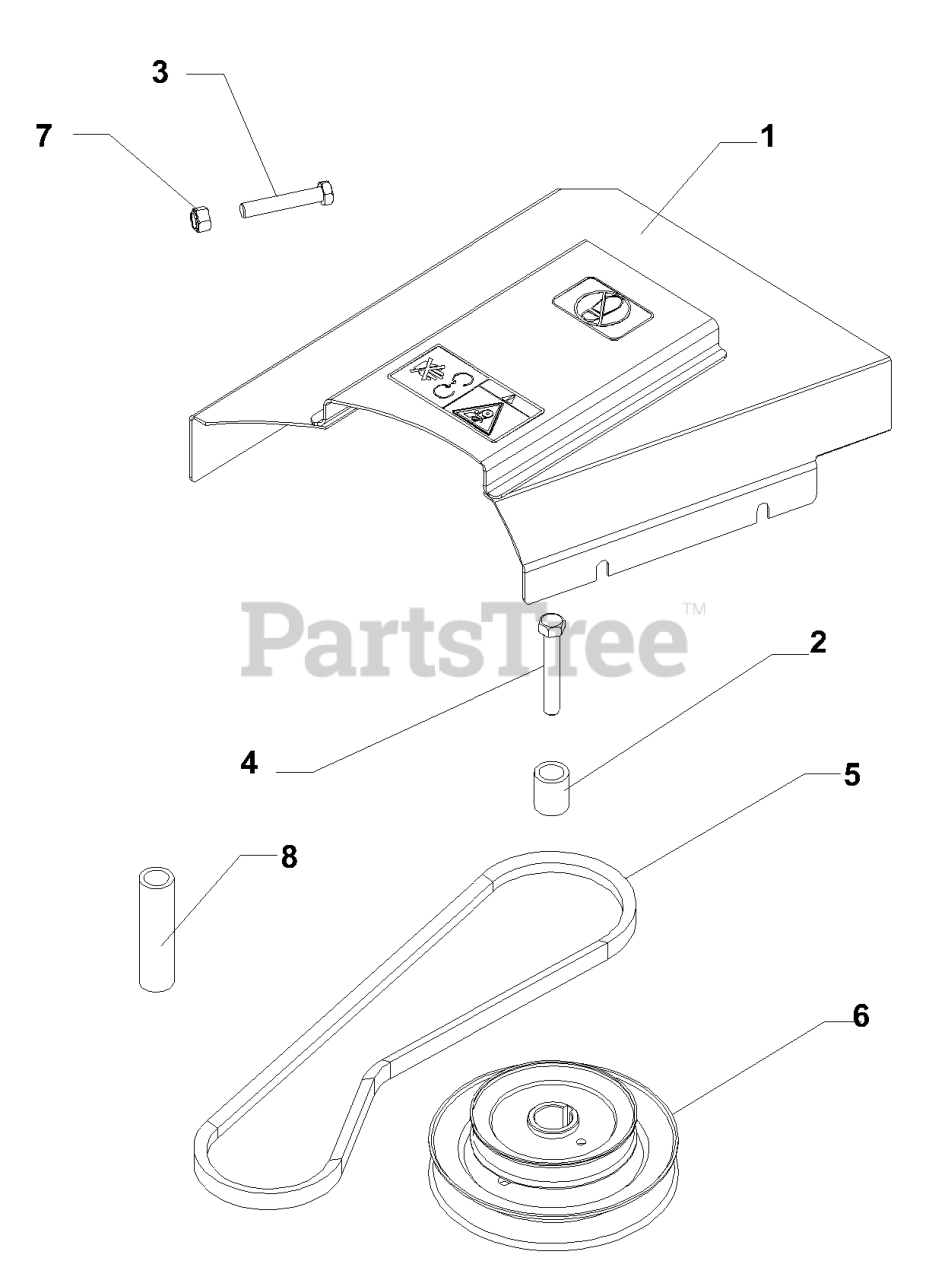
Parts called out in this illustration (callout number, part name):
1	SHIELD W/DECALS-42
1	DNO SHIELD
1	52" SHIELD W/DECALS
1	SHIELD - 61" W/DECALS
3	HCS 3/8C X 2 1/4
3	HCS 3/8C X 1 1/4 GR5
4	BOLT 7/16F X 2 1/2
5	V-BELT 42" SPINDLE DRIVE
5	V-BELT 48" SPINDLE DRIVE
5	V-BELT PUMP DRIVE
5	V-BELT 61" SPINDLE DRIVE
6	STACKED SHEAVE 42-48
6	PULLEY 52"
6	STACKED SHEAVE
7	NUT 3/8-16 NYLOC
